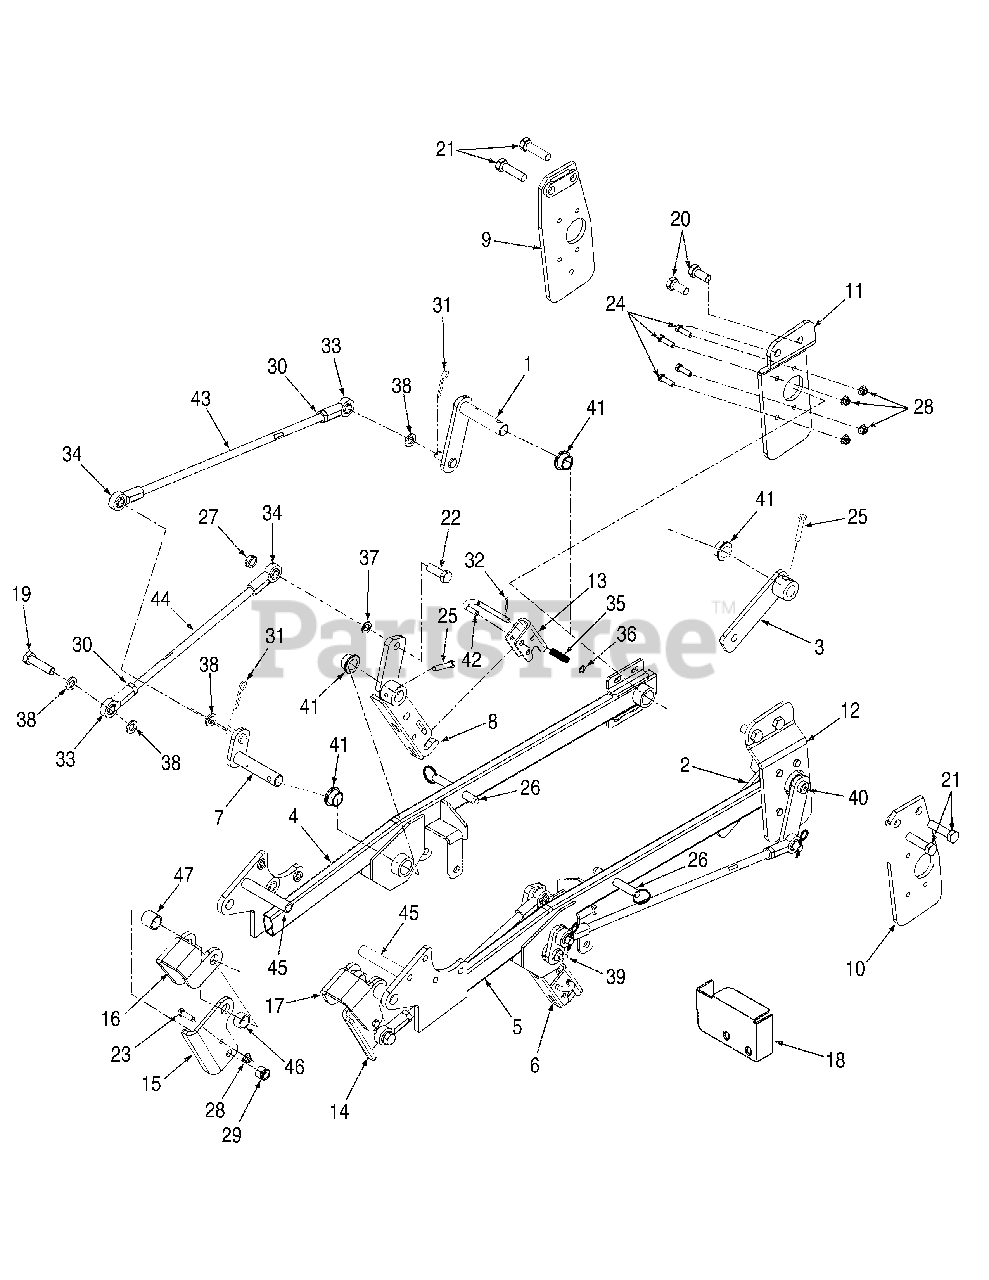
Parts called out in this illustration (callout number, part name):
1	Shaft, Deck Subframe
2	Arm, Front Lift RH
3	Arm, Front Lift LH
4	Rail, Subframe LH
5	Rail, Subframe RH
6	Arm, Rear Lift RH
7	Shaft, Rear Lift
8	Arm, Rear Lift LH
9	Bracket, Loader Adapter LH
10	Bracket, Loader Adapter RH
11	Bracket, Subframe Mounting LH
12	Bracket, Subframe Mounting RH
13	Bracket, Lock Pin
14	Bracket, Breakaway Lift RH
15	Bracket, Breakaway Lift LH
16	Bracket, Lift LH
17	Bracket, Lift RH
18	Cover, Mid PTO
19	Screw, Hex Cap, 5/8-11x 2.5
20	Screw, Hex Cap, M16-2.0 x 35
21	Screw, Hex Cap, M16-2.0 x 60
22	Screw, Hex Cap, 5/8-11 x 1.75 Gr8
23	Screw, Hex Cap, 3/8-16 x 1.25 Gr2
24	Screw, Hex Cap, 3/8-16 x 1.25 Gr5
25	Screw, Hex Cap, 3/8-16 x 2.0 Gr5
26	Pin, .625 Dia.
27	Nut, Jam Lock, 5/8-16 GrA
28	Nut, Hex Flange Insert Lock 3/8-16 GrF
29	Nut, Hex Insert Lock, 5/8-11 Gr5
30	Nut, Hex Jam, 5/8-18 Gr5
31	Pin, Internal Cotter, .125 x 2.5 Lg
32	Pin, Cotter, .125 x .75
33	Ball Joint, .625 ID x 5/8-18
34	Ball Joint, .625 ID x 5/8-18 LH Thrd.
35	Spring, Compression, .531 x 1.75
36	Washer, Flat, .385 x .62 x .063
37	Washer, Flat, .625 x 1.0 x .067 HT
38	Washer, Flat, .64 x 1.12 x .125
39	Fitting, Lube
40	Fitting, Lube
41	Bearing, Flange, 1.0 x 1.125 x 1.62
42	Rod, Deck Release
43	Rod, 23.735 Lg LH/RH Thrd.
44	Rod, 15.25 Lg LH/RH Thrd.
45	Spacer, .625 x 4.95
46	Spacer, 1.25 x .625
47	Spacer, 1.25 x 1.25
